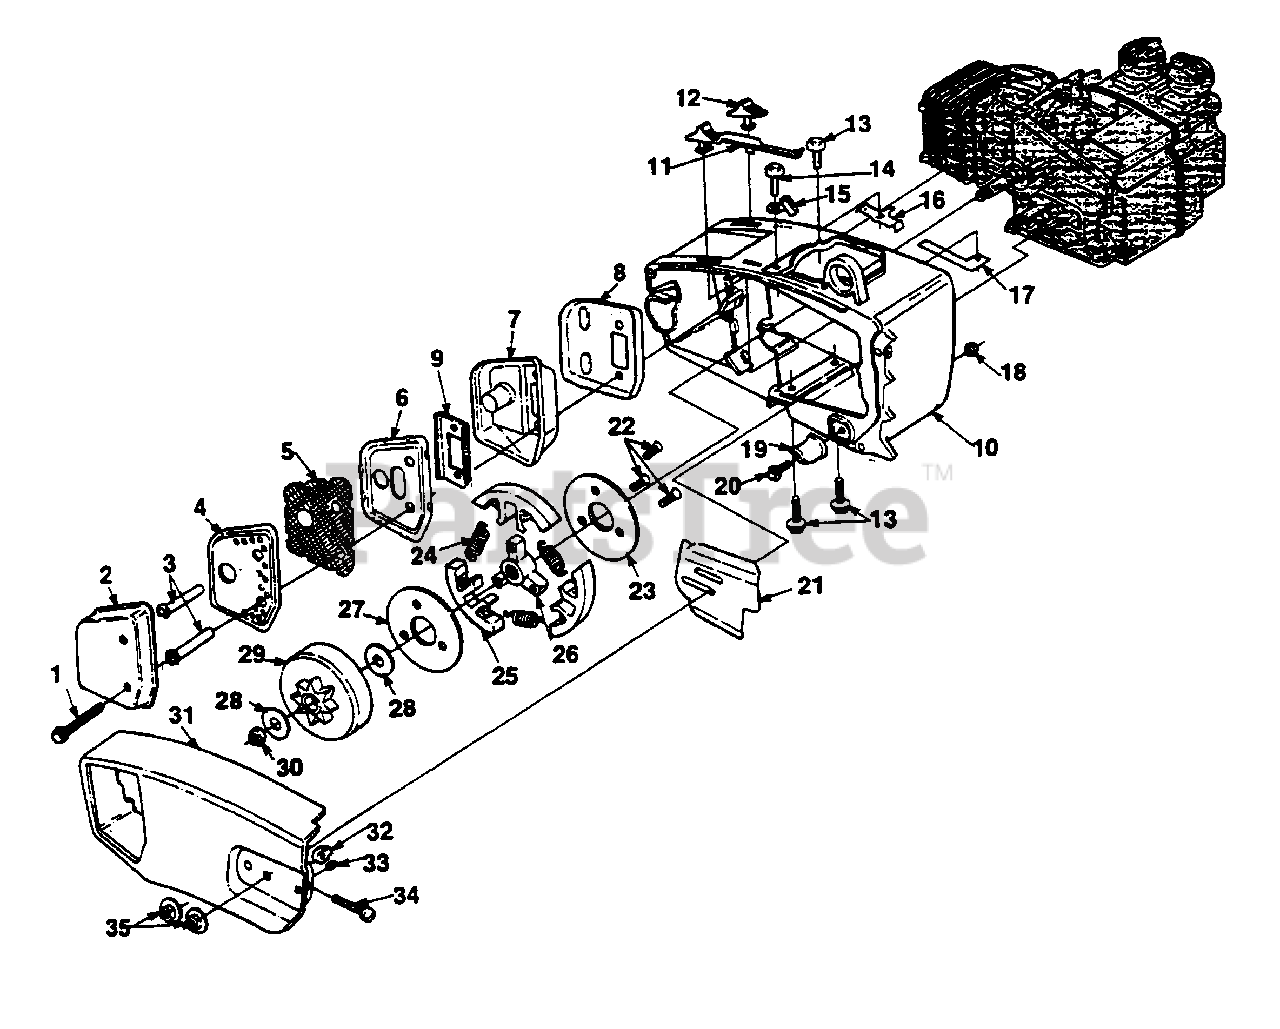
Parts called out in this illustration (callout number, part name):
2	CAP- Muffler
4	BAFFLE- Muffler
5	SCREEN- Spark arrestor
6	BAFFLE- Muffler
7	BODY- Muffler
8	DEFLECTOR- Exhaust
9	PLATE- Muffler
10	HOUSING- Engine
11	BUTTON- Choke
12	BUTTON- Stop switch
13	SCREW- Hex Sems 10-24 x 5/8
14	SCREW- 10-24 x .625
15	BRACKET- Cable
16	SPRING- Stop switch
17	CONTACT- Stop switch
18	NUT- Lock 10-24
19	STOP- Chain
20	SCREW- Mach. hex 10-24 x 5/8
21	PLATE- Guide bar
22	SCREW- Flat hd. 7/16-18
23	COVER- Clutch (outer)
24	SPRING- Ext.
25	SHOE- Clutch
26	SPIDER- Clutch
27	COVER- Clutch (inner)
28	WASHER- Thrust
29	SPROCKET & DRUM 6T
30	NUT- Lock 5/16-24
31	COVER- Drivecase
32	PIN- Guide bar adjusting
33	"E" RING
34	SCREW- Guide bar adjusting
35	NUT- Flange 1/4-20
